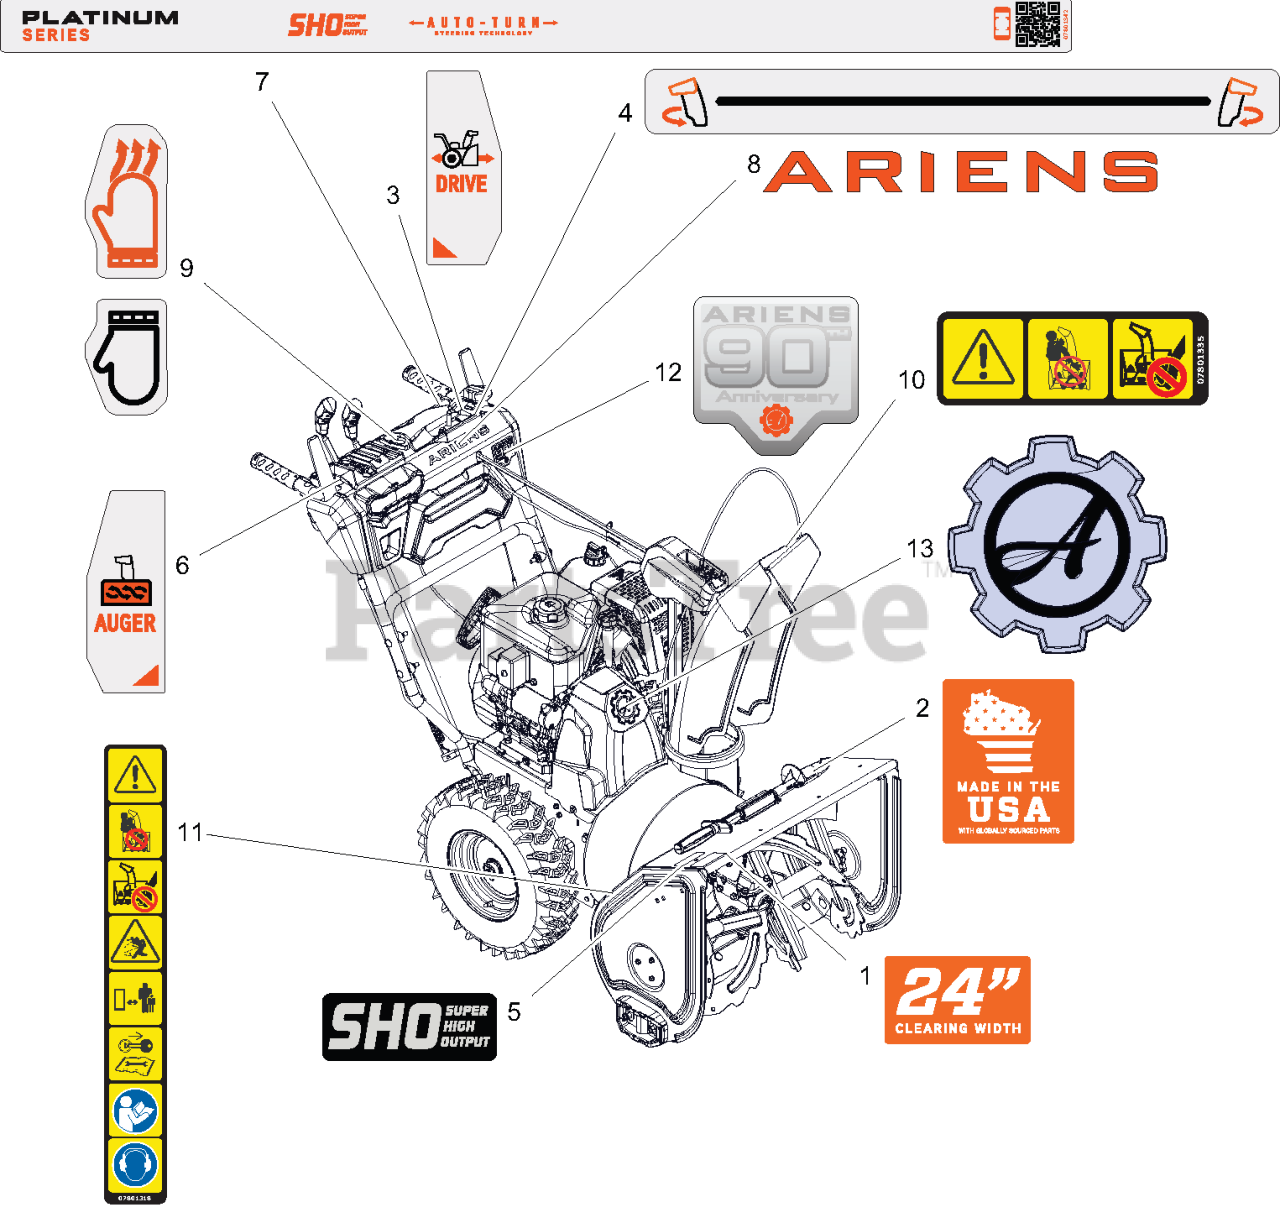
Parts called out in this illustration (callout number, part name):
1	DECAL- CLEARING - 24
2	DECAL- MADE IN USA
3	DECAL-CONTROL-DRIVE WHEEL 90TH
4	DECAL- CHUTE ROTATION 90TH
5	DECAL, SHO
6	DECAL- CONTROL - AUGER 90TH
7	DECAL- DASH - PLT 90TH
8	DECAL- ARIENS - 7.46" 90TH
9	DECAL- HOT GRIP SWITCH 90TH
10	DECAL- DANGER
11	DECAL- SAFETY - DANGER
12	DECAL, BADGE-90TH ANNIVERSARY
13	DECAL- ARIENS GEAR BADGE
